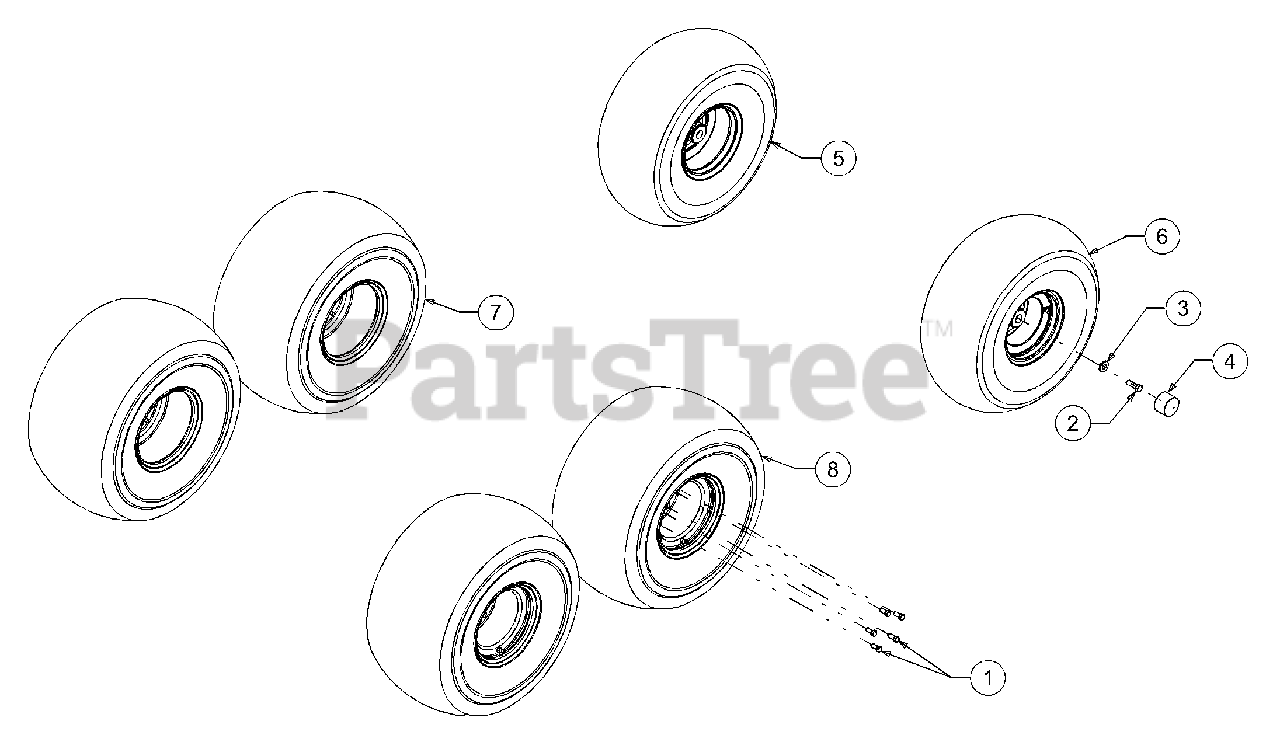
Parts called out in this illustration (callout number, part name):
1	Hex Screw, 7/16-20 x 1.5, Gr5
2	Hex Screw, 1/2-13 x 1.5, Gr5
3	Washer, Flat, .531 x 1.25 x .181
4	Dust Cover
5	Tire Assembly, 22 x 11 x 10 LH
6	Tire Assembly, 22 x 11 x 10 RH
7	Wheel Assembly, 25 x 11 x 10 LH
8	Wheel Assembly, 25 x 11 x 10 RH
